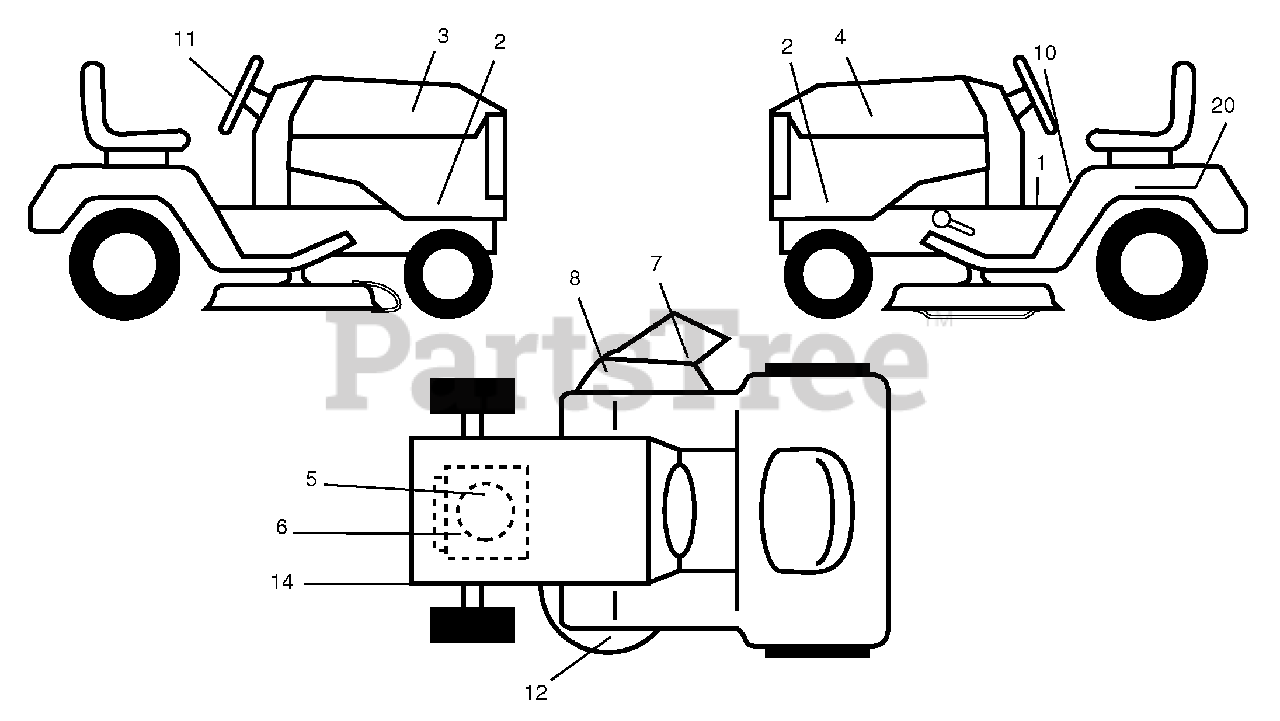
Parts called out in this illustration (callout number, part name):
1	Decal Oper. Step Thru Eng/Fr
2	Decal Side Panel
3	Decal Hood RH
4	Decal Hood LH
5	Decal Hood Cust.
6	Decal Engine
7	Decal Deck B 42
8	Decal Warning
10	Decal Fender Danger Eng/Fr
11	Decal SW Husq Inter
12	Decal deck Sears heavyduty
14	Decal V-Belt Schematic
20	Decal Bat Dan/Psn
20	Decal Handle Lft Height Adjust
20	Decal Bypass Lt Hydro
20	Decal Replc Part
